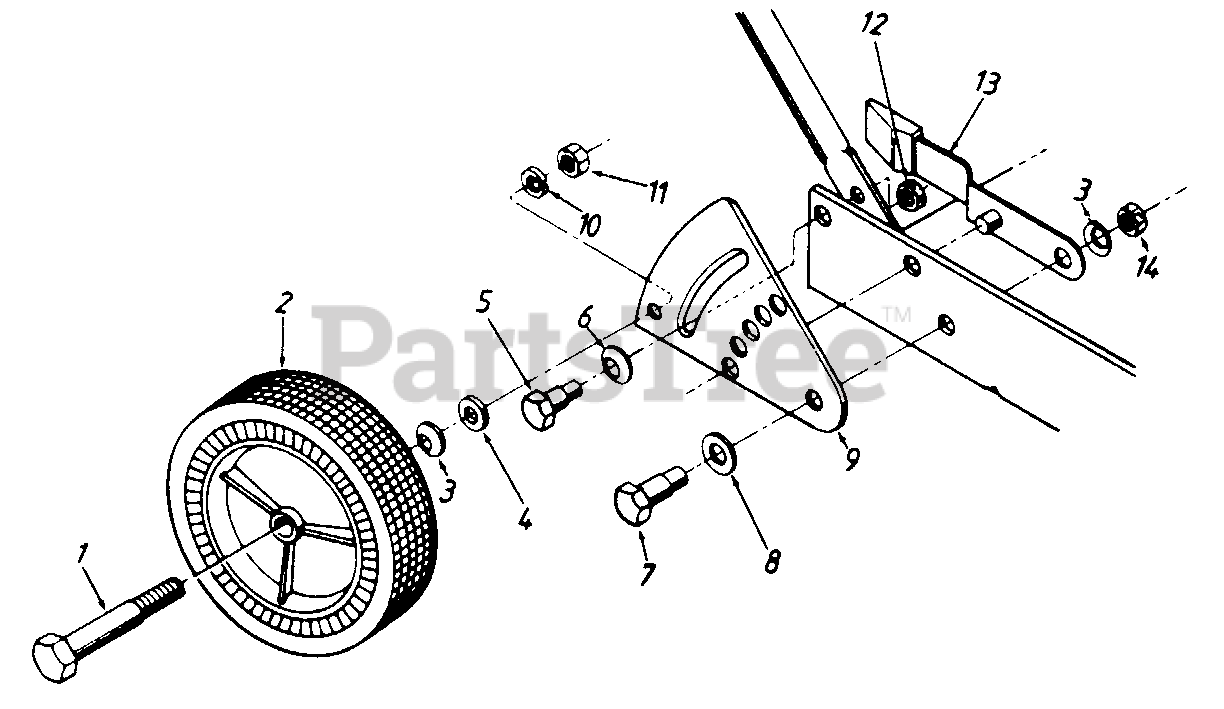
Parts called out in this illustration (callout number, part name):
1	SCREW-SHLD .498 DIA X 1.450
2	WHEEL ASSY W/TIRE
3	WASHER-BELL .400 ID X .88 X .060
4	WASHER-FL
5	BOLT-SHLD
6	WASHER-BELL .515X1.4
7	SCREW-SHLD
8	WASHER-FL .510 X .995 X .060
11	NUT-HEX 3/8-16
12	NUT-HEX CENTER L-3/8-16
13	LEVER-SPRING ADJ
14	NUT-HEX CENTER L-JAM
